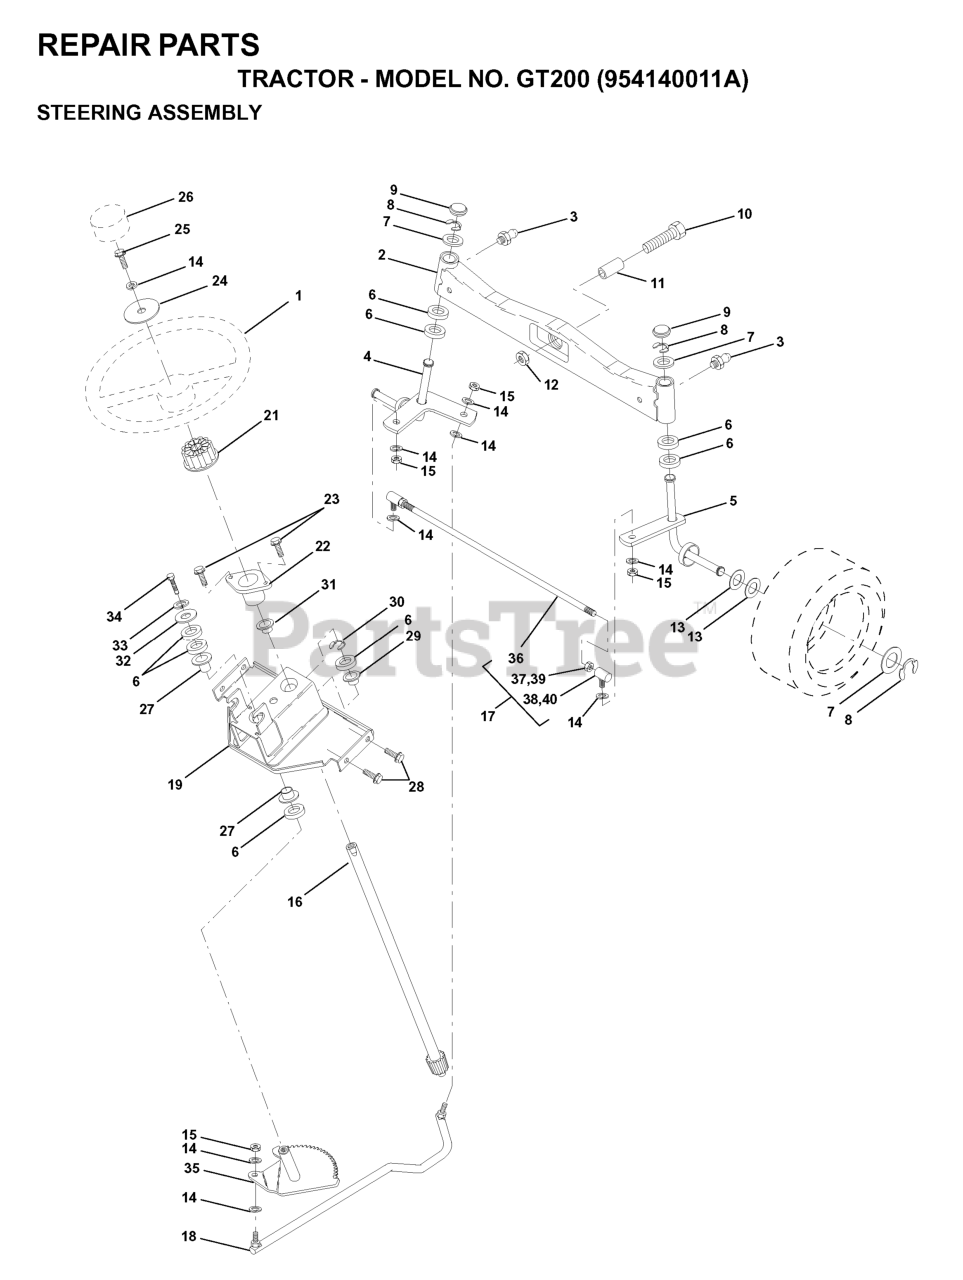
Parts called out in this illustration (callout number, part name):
1	STEERING WHEEL
2	FRONT AXLE ASSY
3	ZERK M
4	SPINDLE ASSY LH
5	SPINDLE ASSY RH
6	THRUST WASHER
9	CAP.SPINDLE.BLACK
10	Bolt, Hex 5/8 -11 x 2 - 3/4 Gr. 5
11	TUBE, PIVOT AXLE
12	NUT-LOC,FLANGE LT
14	WASHER, LOCK 3/8
15	GRIPCO NUT
16	SHAFT ASM, STEERING
17	ROD ASSY/TIE BALL
18	DRAGLINK-BALL JOINT SOLID
19	SUPPORT ARM, STEERING VGT
21	ADAPTER LT
22	BUSHING, STRG. BLK
23	SCREW.TT.#10-32X.5.3/8.FLANGE
24	WASHER T
26	INSERT,STR WHEEL
27	BRNG T
28	SCREW
29	BEARING-FLANGE GT
30	Ring, Klip Truarc #5304-75
31	BUSHING.NYLINER.
33	WASHER.LOCK.HVY.HLCL.SPR.5/16
34	BOLT
35	GEAR.ASM.SECTOR.
36	TIE ROD
38	JOINT
